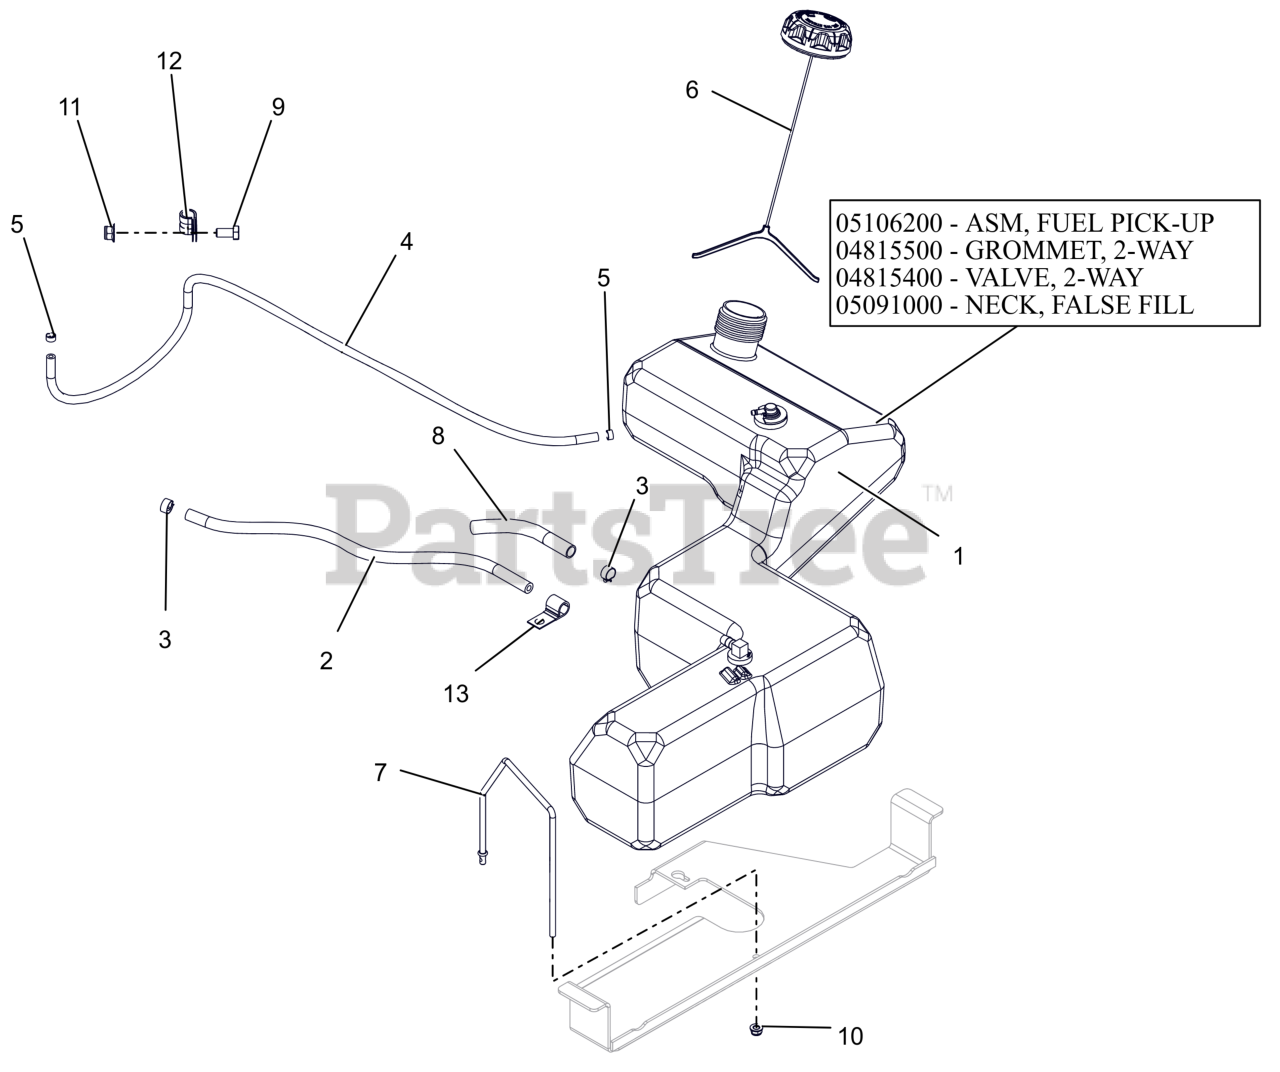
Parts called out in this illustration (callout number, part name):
1	ASSY, FUEL TANK-IKON
1	ASM, IKON FUEL PICK-UP
1	GROMMET, 2-WAY
1	VALVE, 2-WAY
1	NECK, FALSE FILL-2017 IKON
2	HOSE, .25 LOW-PERM BULK GAS
3	CLAMP, FUEL LINE
4	HOSE, .188 LOW-PERM BULK GAS
5	CLAMP-HOSE, SPRING .188
6	CAP, FUEL VENT-IN 2.25" RATCH.
7	BRKT, FUEL TANK HOLD DOWN
8	WRAP, ANTIABRASION .5X.064WALL
9	@BLT-HEX .38-16X.75 GR5 YWZC
10	@NUT-LK-NYL-FLG .25-20 YWZC
11	@NUT-LK-NYL-FLG .38-16 YWZC
12	CLAMP, CUSHIONED STEEL
13	J-CLAMP
